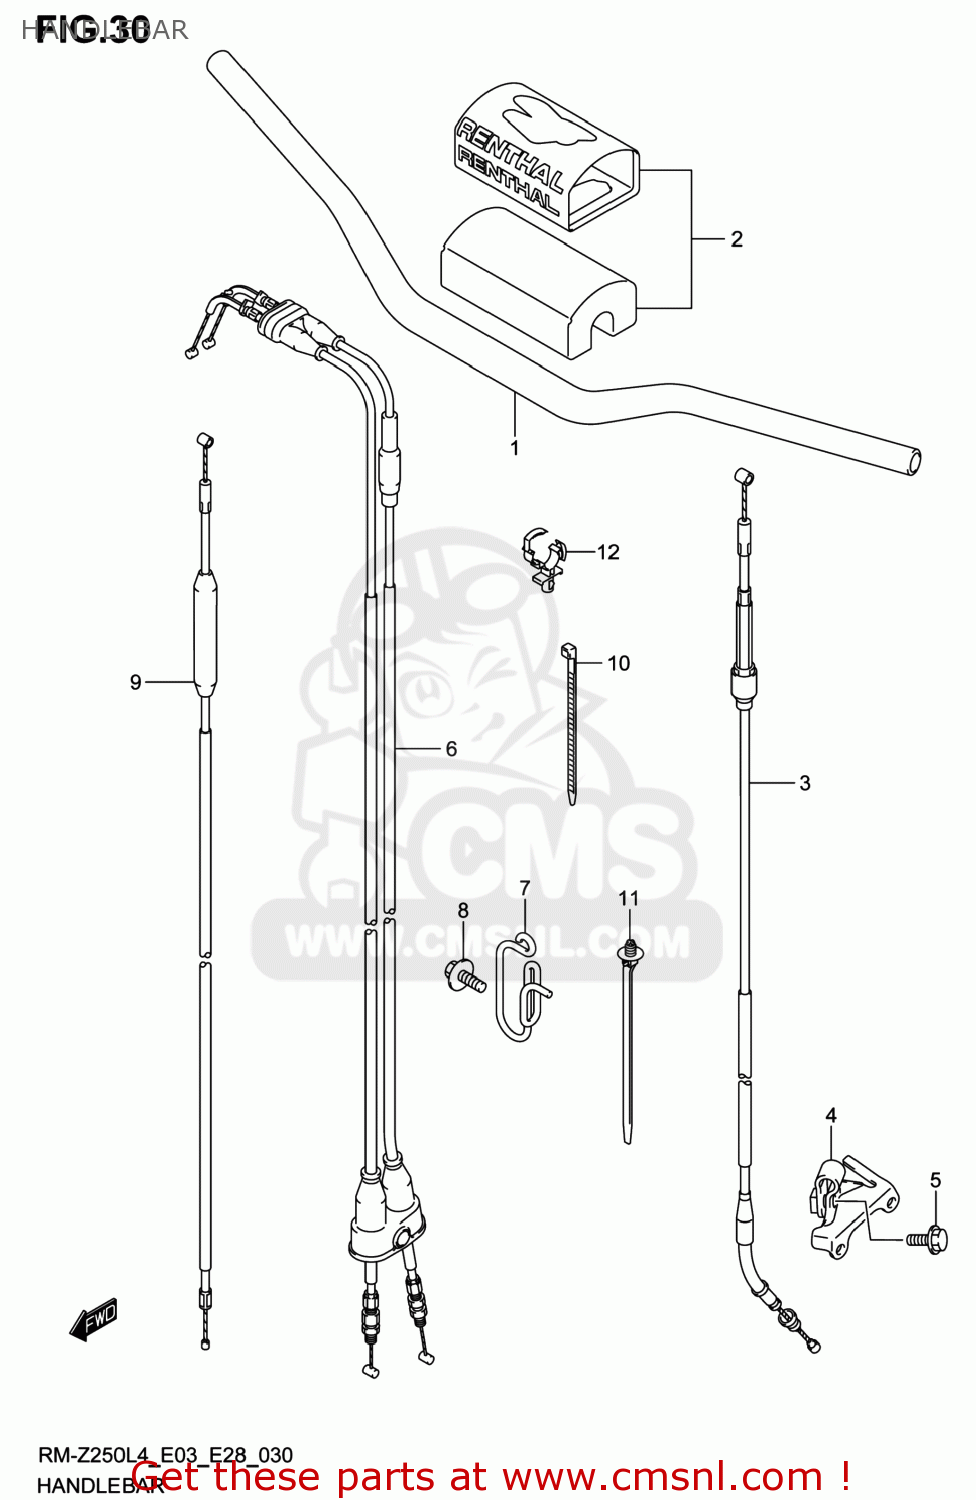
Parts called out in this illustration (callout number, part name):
1	HANDLEBAR
2	PAD SET,HANDLEBAR (NAS)
3	CABLE ASSY,CLUTCH
4	BRACKET,CLUTCH CABLE
5	BOLT
6	CABLE SET,THROTTLE
7	GUIDE,THROTTLE & STARTER CABLE
8	SCREW(6X16)
9	CABLE ASSY,HOT STARTER
10	CLAMP(L:145)
11	CLAMP(L:154)
12	CLAMP
